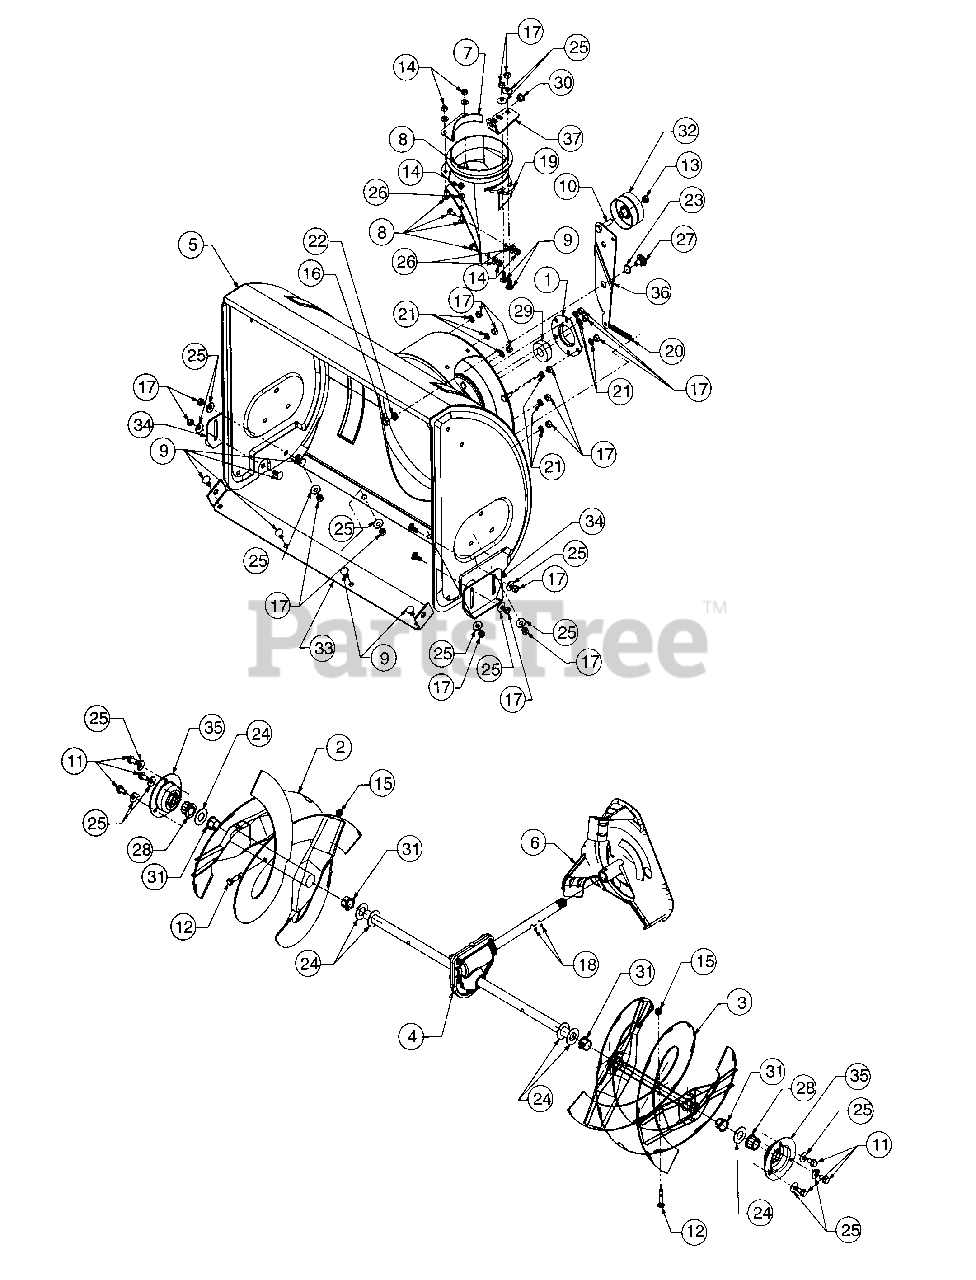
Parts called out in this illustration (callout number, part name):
1	Bearing Housing
8	Carriage Screw 1/4-20 X .62
9	Carriage Bolt 5/16-18 X .75
10	Hex Screw 3/8-24 X 1.5 Grade 5
11	Hex Washer Head TT-Screw 5/16-18 X .62
12	Shear Bolt 5/16-18 X 1.5
13	Jam Lock Nut
14	Toplock Nut 1/4-20
15	Hex Lock Nut 5/16-18
16	Hex Nut 3/8-16
17	Hex Nut 5/16-18
18	Spiral Pin
19	Chute Adapter
20	Extension Spring
21	Lock Washer 5/16
22	Lock Washer 3/8
23	Wave Washer
24	Flat Washer .76 I.D. x 1.49 O.D.
25	Bell Washer .345 I.D. x .88
26	Flat Washer 1/4 x .630
27	Shoulder Screw
28	Hex Flange Bearing
29	Bail Bearing
30	Plastic Bushing
31	Flange Bushing
32	Flat Idler
